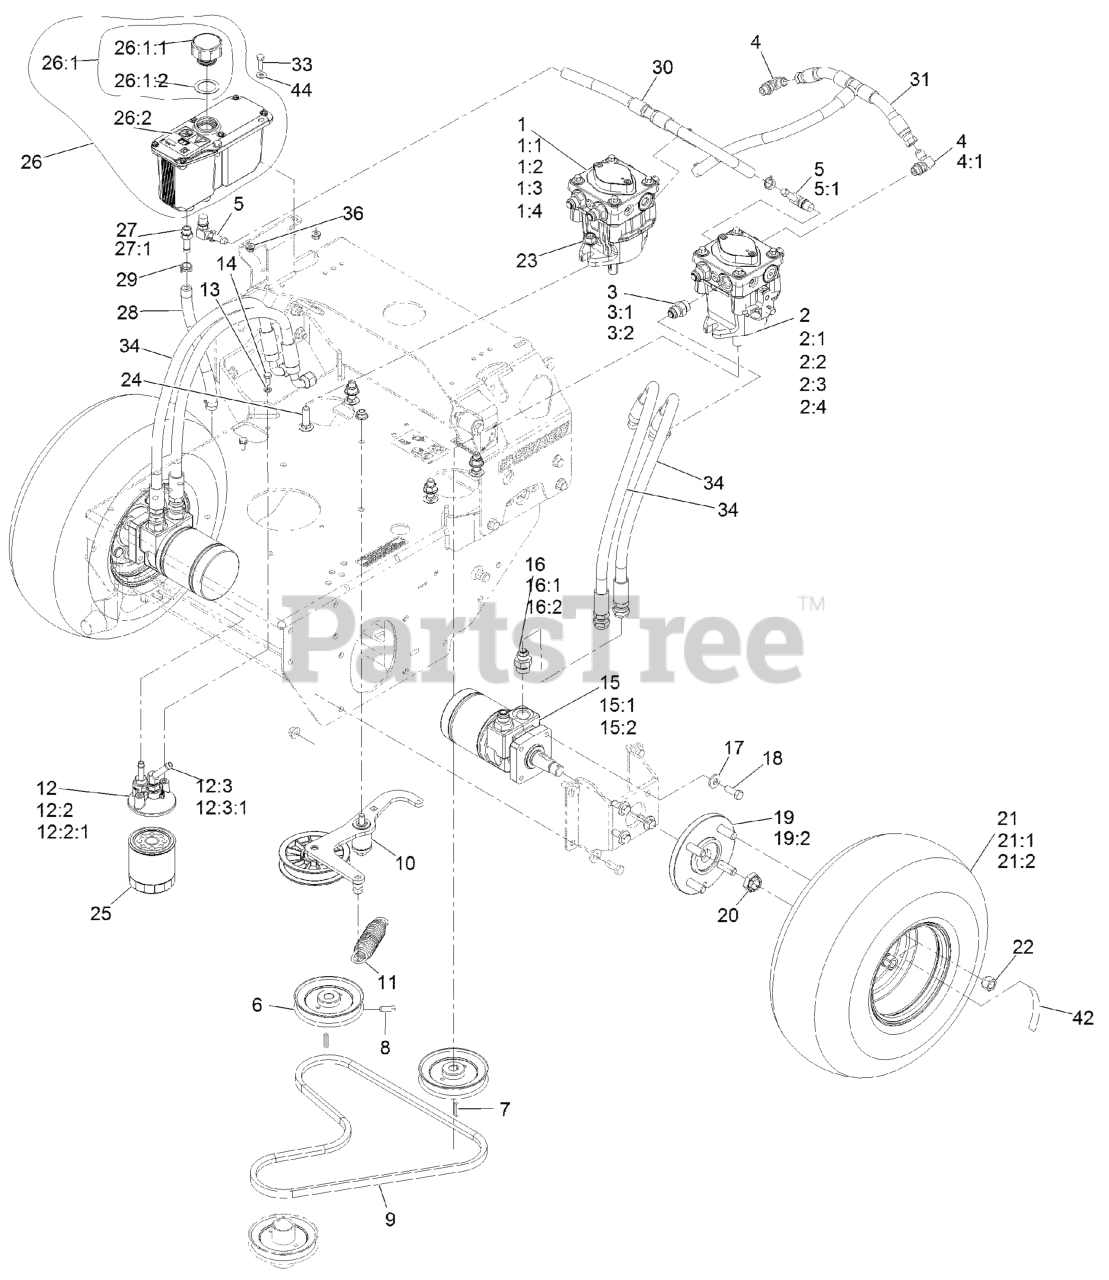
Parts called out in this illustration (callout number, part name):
1	RH HYD PUMP ASM
1:1	INPUT SHAFT KIT
1:2	BEARING-THRUST
1:3	CYLINDER BLOCK KIT
1:4	SEAL OVERHAUL KIT
2	LH HYD PUMP ASM
2:1	INPUT SHAFT KIT
2:2	BEARING-THRUST
2:3	CYLINDER BLOCK KIT
2:4	SEAL OVERHAUL KIT
3	FITTING-STRAIGHT
4	FITTING-ELBOW, 90 DEG
4:1	O-RING
5	FITTING-ELBOW, 90
5:1	O-RING
6	SHEAVE ASM
8	SCREW-SET, SQH
9	BELT
10	ASM, PUMP IDLER
11	SPRING-EXTENSION
12	ASM, FILTER HEAD
12:2	ADAPTER-STRAIGHT
12:2:1	O-RING
12:3	FITTING-BARBED, 45 DEG
12:3:1	O-RING
13	WASHER-LOCK
14	SCREW-HH
15	HYD MOTOR ASM
15:1	SEAL KIT
15:2	BEARING AND SEAL KIT
16	FITTING-STRAIGHT
16:1	O-RING
17	WASHER-BELLEVILLE
18	SCREW-HH
19	WHEEL HUB ASM
19:2	STUD-WHEEL
20	NUT-LOCK
21	WHEEL AND TIRE ASM
21:1	TIRE-TURFMASTER
21:2	RIM-WHEEL
22	NUT-LUG
23	NUT-HF, NI
24	BOLT-CARR
25	FILTER-25 MICRON, BI-DIRE
26:1	Reservoir-HYD
26:1:1	Cap-Reservoir, HYD
26:1:2	GASKET-CAP
26:2	DECAL-WARNING
27	ADAPTER-STRAIGHT
27:1	O-RING
28	HOSE-CHARGE
29	CLAMP-HOSE
30	HOSE-CASE DRAIN
31	HOSE-CHARGE
33	SCREW-HH
34	HYD HOSE ASM
36	NUT-HHF
42	DECAL-TORQUE WHEEL LUG-HU
44	WASHER-FLAT
